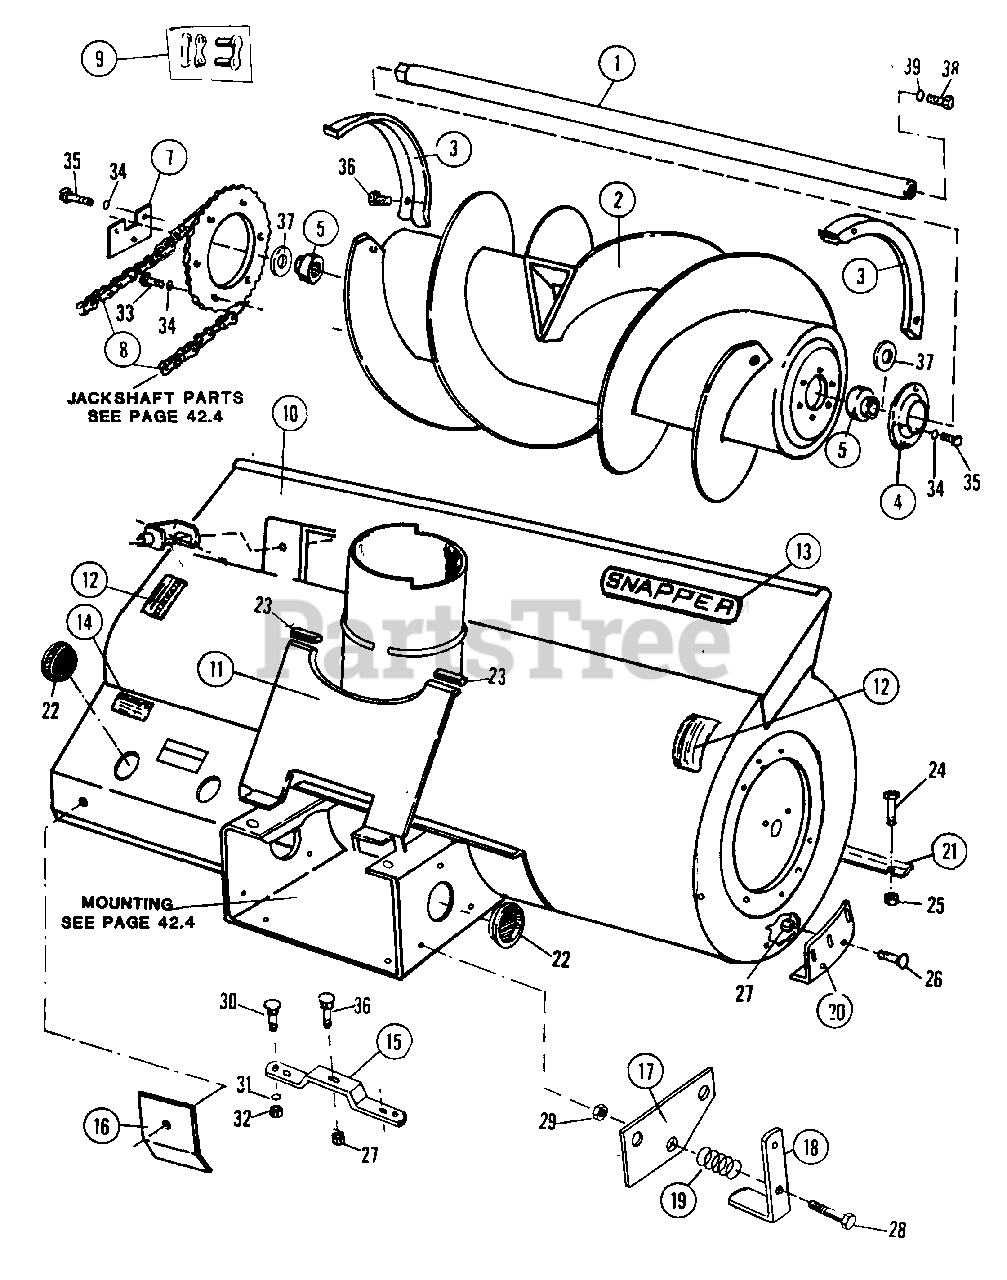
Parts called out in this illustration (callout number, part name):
1	SHAFT, AUGER
2	AUGER, 42" UNIT
3	GUARD, CHAIN & BEARING
4	FLANGETTE
5	BEARING, AUGER SHAFT
7	PLATE, AUGER MOUNTING
8	CHAIN, AUGER DRIVE
9	KIT, CHAIN REPAIR
10	HEADER, 42" SNOW THROWER
11	COVER, CHANNEL
12	DECAL, WARNING (SPINNING BLADES)
13	DECAL, SNAPPER
14	DECAL, CAUTION (STOP MACHINE)
15	BRACKET, CHANNEL COVER MOUNTING
16	PLATE, REINFORCEMENT
17	PLATE, KICKSTAND MOUNTING
18	KICKSTAND
19	SPRING, KICKSTAND
20	SHOE, SKID
21	BLADE, SCRAPER
22	PLUG, BUTTON
23	MOLDING, RUBBER
24	BOLT, 1/4-20x5/8 CARRIAGE
25	LOCKNUT, 1/4-20 FLANGE
26	BOLT, 5/16-18 x 3/4 CARRIAGE
27	LOCKNUT, 5/16-18 NYLON CENTER
28	BOLT, 3/8cx1-1/4 HEX HEAD
29	LOCKNUT, 3/8c HEX
30	BOLT, 3/8cx1" CARRIAGE
31	LOCKWASHER, 3/8"
32	NUT, 3/8c HEX
33	BOLT, 5/16-18x3/4 HEX HEAD
34	LOCKWASHER, 5/16"
35	BOLT, 5/16-18x5/8 HEX HEAD
36	SCREW, 1/4-14x1/2 SPECIAL
37	SPACER, AUGER BEARING
38	BOLT, 1/2-13x1-1/4 HEX HEAD
39	LOCKWASHER, 1/2"
